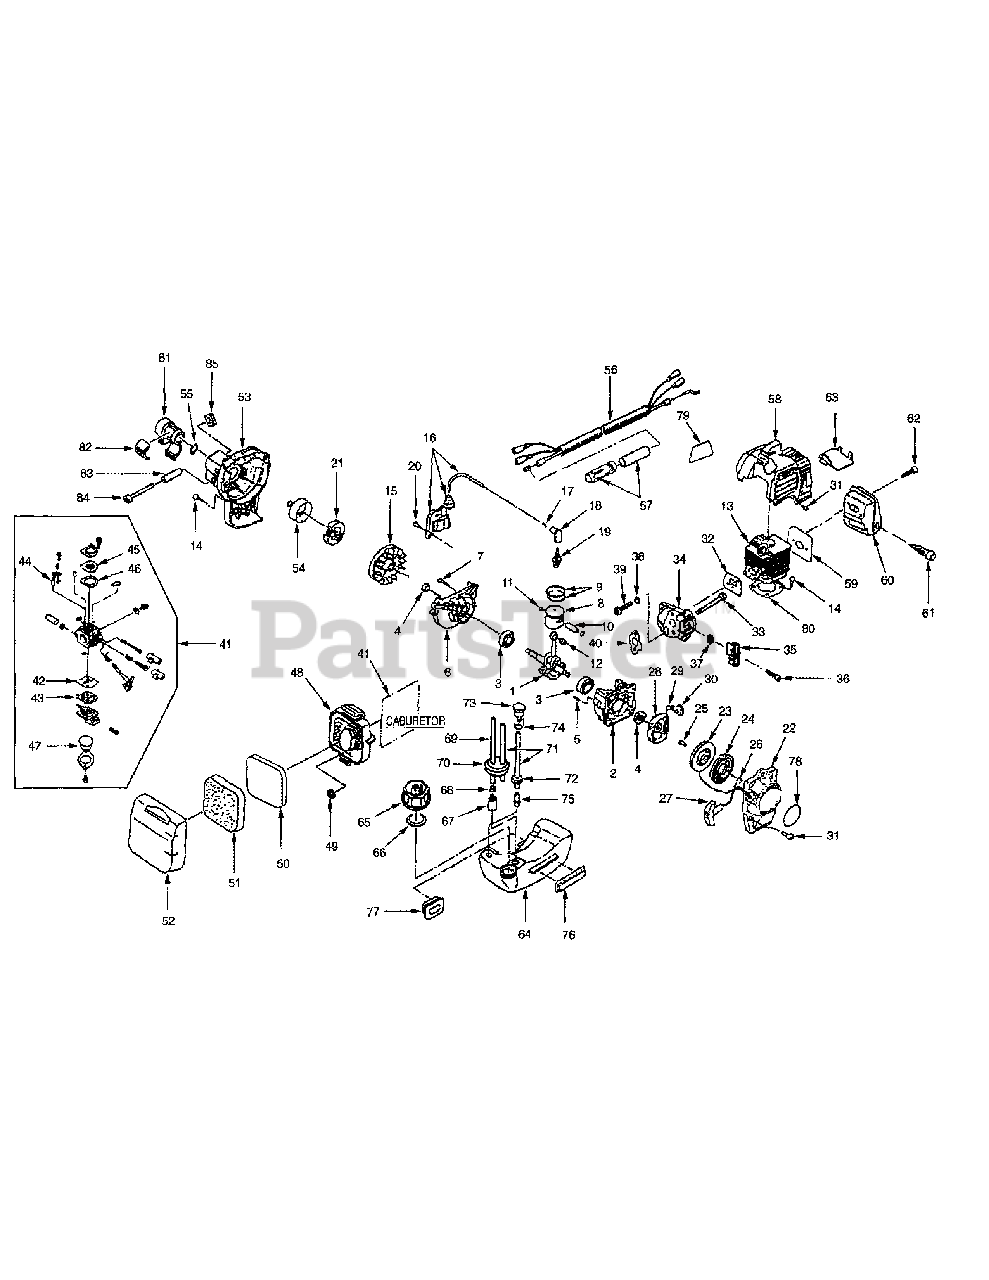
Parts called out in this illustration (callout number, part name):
2	Crankcase Assembly
3	Bearing Ball, 6201
6	Crankcase Assembly
8	Piston Assembly
9	Ring, Piston
11	Clip, Piston Pin
12	Beairng, Needle
15	Flywheel, Magneto
16	Coil Assembly, Ignition
19	Spark, Plug
21	Clutch Assembly
22	Recoil Assembly
24	Spring, Spiral
26	Rope, Starter
27	Knob, Starter
28	Pulley Assembly, Starter
29	Spring, Return
32	See Ref. 86 - Gasket, Insulator
38	Washer
40	See Ref. 86 - Gasket
41	Carburetor Assembly
42	Diaphragm, Pump
43	Gasket, Pump
44	Valve, Float
45	Diaphragm, Metering
48	Case, Air Silencer
50	Element "B", Air Filter
51	Element "A", Air Filter
53	Housing, Blower
54	Drum, Clutch
55	Snap Ring, S-12
56	Wire Complete, Throttle
58	Cowling, Cylinder
59	See Ref. 86 - Gasket, Muffler
63	Plate, Baffle
65	Cap Assembly, Fuel Tank
67	Filter, Fuel
69	Hose
71	Hose
73	Valve, Revrsing
76	Rubber
80	Gasket, Cylinder
